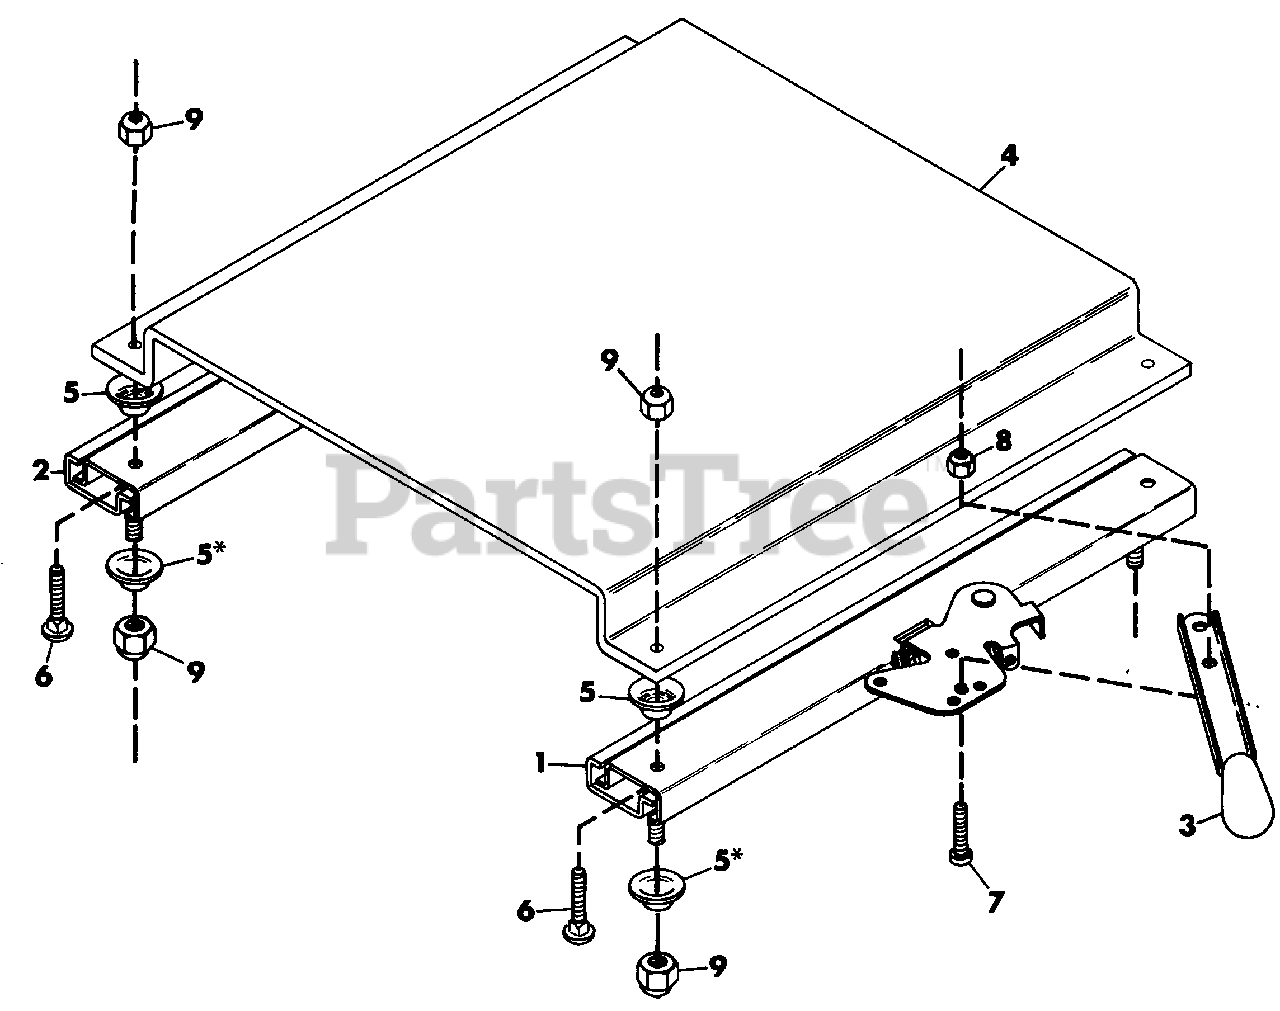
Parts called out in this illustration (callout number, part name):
1	ADJUSTER, SEAT W/LATCH
2	ADJUSTER, SEAT
3	HANDLE, SEAT ADJUSTER
4	PLATE, SEAT
5	SPACER
6	BOLT, CARRIAGE 5/16-18X1.00
7	SCREW, MACHINE 10-24X.625 P/HD
8	NUT, LOCK 10-24
9	NUT, LOCK 5/16-18
